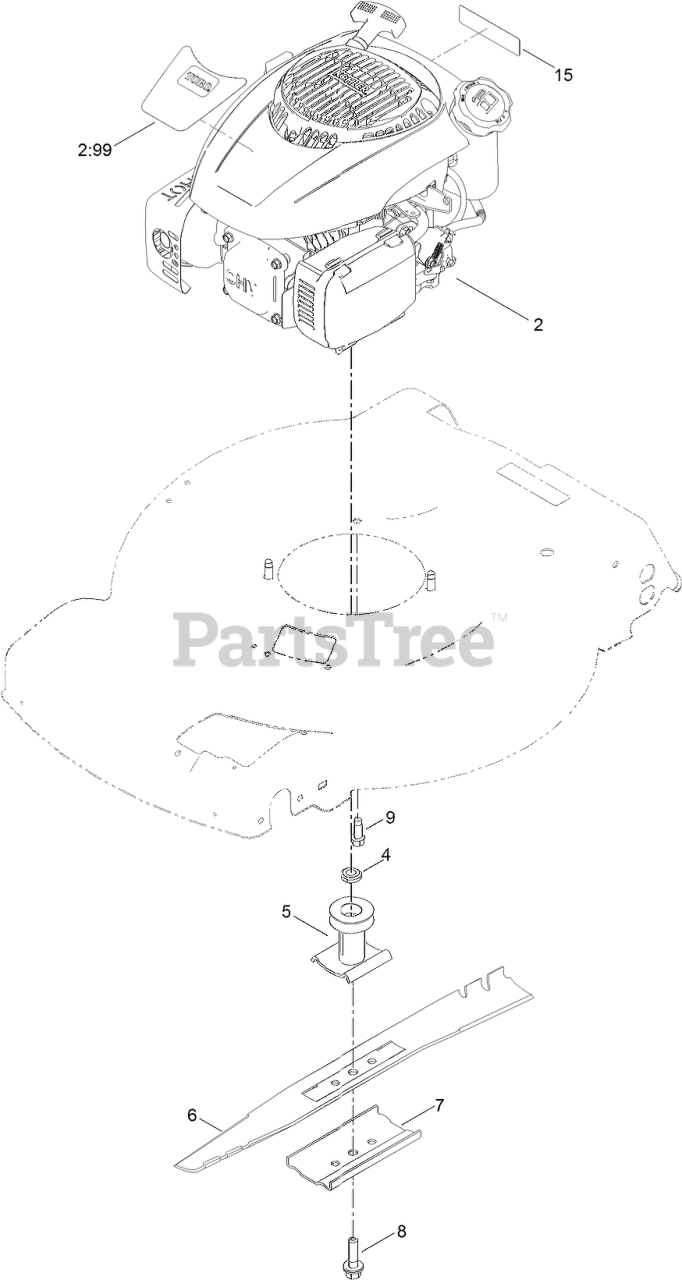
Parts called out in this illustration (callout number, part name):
2:99	DECAL-SHROUD
4	SPACER-DRIVER
5	DRIVER-BLADE
6	BLADE-22 INCH
7	SUPPORT-BLADE
8	BOLT-BLADE
9	SCREW-TAPTITE
15	DECAL-ARRESTOR, SPARK
